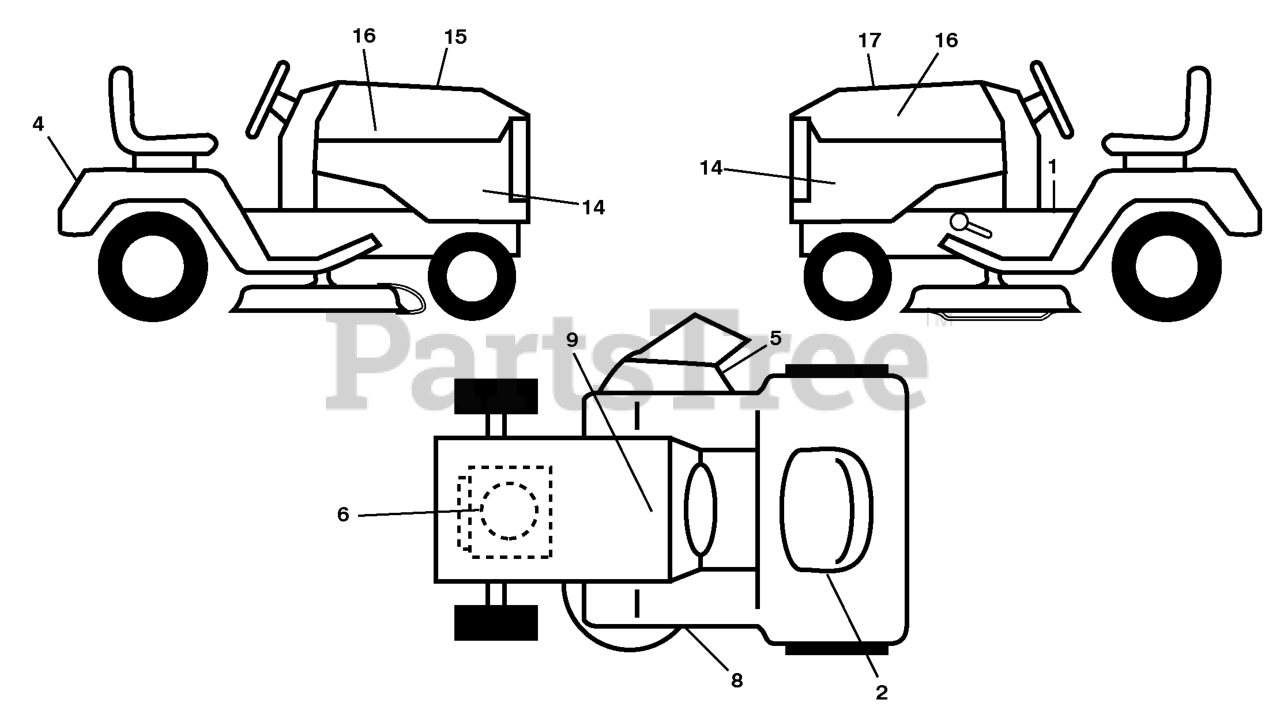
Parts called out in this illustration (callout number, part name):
1	DECAL.WARN.START.INSTRUCTIONS
2	DECAL,ETHANOL E85 WARNING
4	DECAL.FENDER
5	DECAL.MOWER
6	DECAL.ENG.BS.23HP.XRD.TWIN
8	DECAL.MOWER.SCH.48/54
9	DECAL BTRY SYMBOLS
14	DECAL, PANEL SIDE
15	DECAL.WARNING.CUST.RESP.E85.
16	RP.DECAL.BADGE.170MM.TEXTLOGO
17	DECAL.RPL.BSM44.INK.TLW.48.K4
